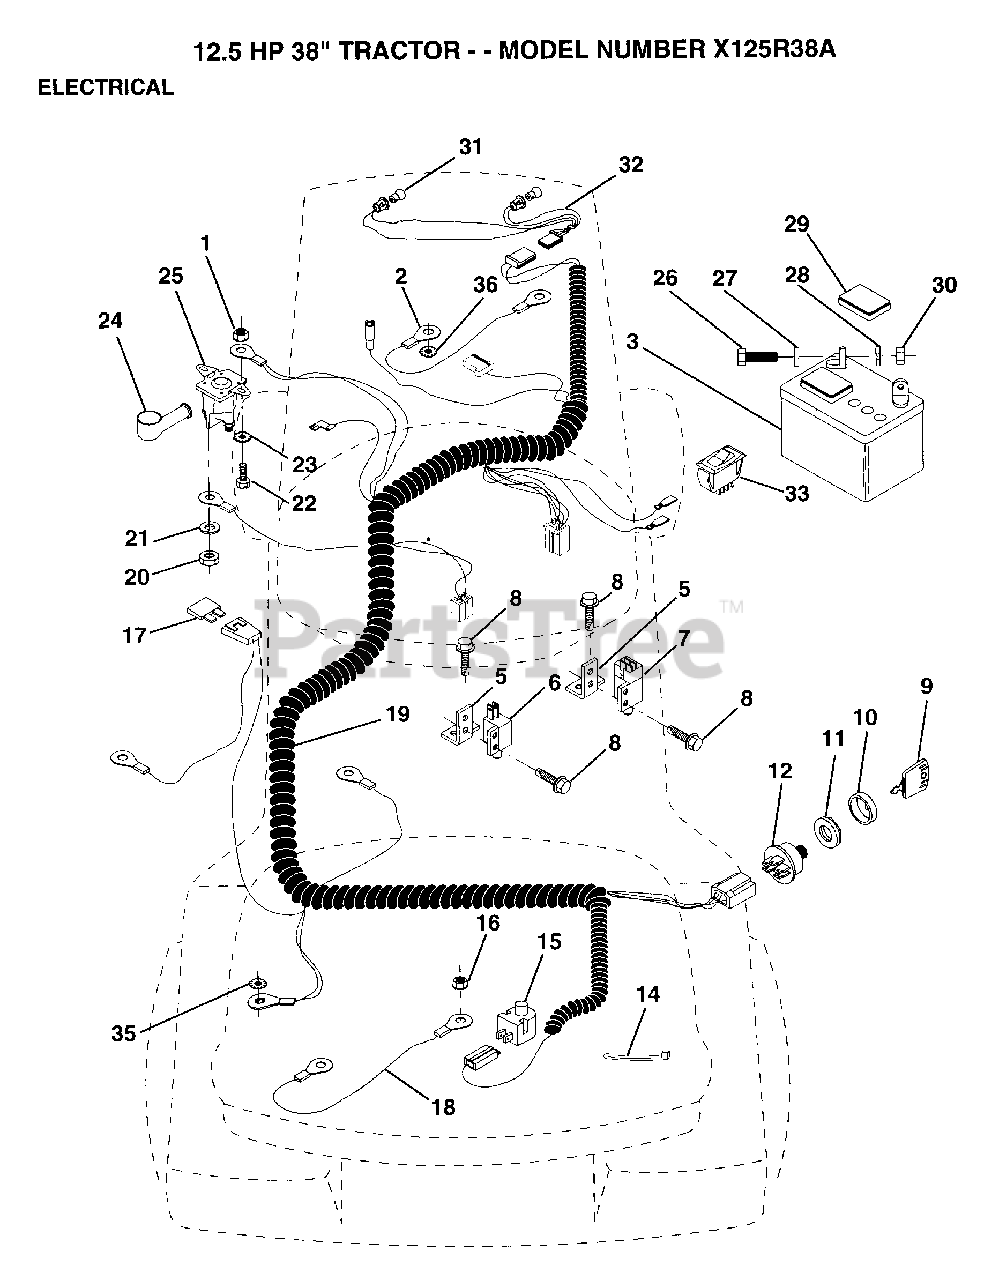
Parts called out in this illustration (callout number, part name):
1	NUT
2	CABLE ASM.
5	BRACKET LT
6	SWITCH-INTER. GT
7	SWITCH INTERLOCKT
8	SCREW
9	KEY
11	NUT IGNITION
14	WIRE TIE
15	SWITCH SEAT
17	FUSE HYT
18	CABLE ASSY
20	NUT
22	BOLT
26	BOLT LT
27	WASHER
28	LOCKWASHER
29	"CAP,BATTERY "
33	SWITCH LT
35	LOCKWASHER
36	LOCKWASHER
